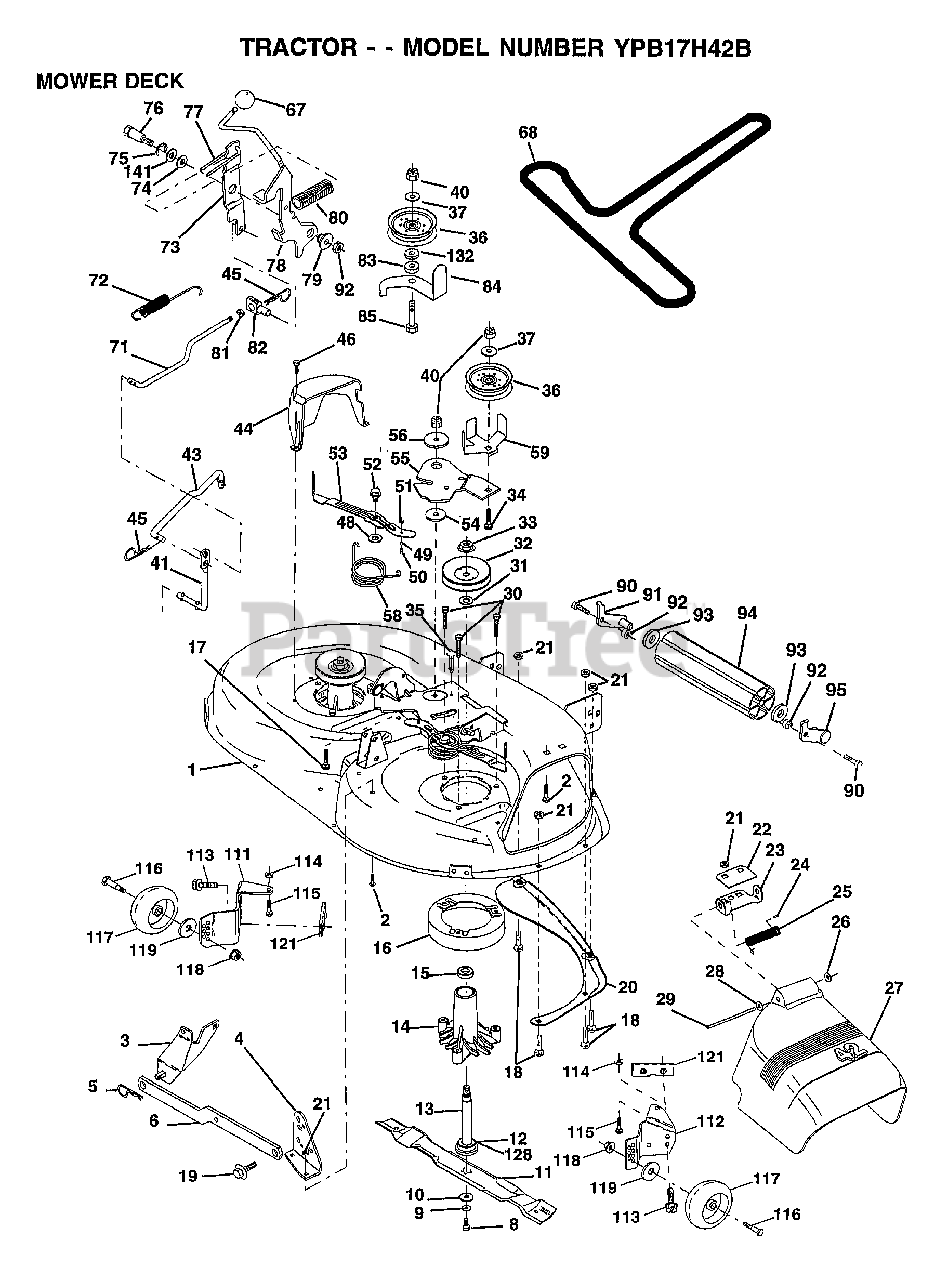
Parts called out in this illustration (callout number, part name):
1	"HOUSING ASSY.42"""
2	BOLT
3	BRKT ASM SWAY BAR
4	BRKT DECK SW BAR
8	BLADE BOLT
10	WASHER.HARD.BLADE
11	"BLADE.42"" HIPERF"
12	BEARING.BALL
14	HSG ASM MANDREL
15	BEARING
16	STRIPPER RND MWR
17	BOLT RDHD 3/8-16
18	BOLT
19	BOLT SHD 5/16-18
20	BAFFLE VORTEX 42
22	STIFFENER BRKT
23	DEFLECTOR BRKT
24	CAP-SLEEVE LT
25	SPRING TORSION
26	NUT PUSH M
27	DEFLECTOR.SHIELD
28	WASHER
29	HINGE ROD
30	"SCREW-THD ROLL,WA"
31	WASHER
32	PULLEY.MANDREL.42
34	BOLT
35	XMAS TREE FASTNER
36	FLAT IDLER PULLEY
37	WASHER
41	PIVOT ROD
43	ROD CLUTCH W/NIBS
44	GUARD MAND LH BLK
45	RETAINER M
46	SCREW.1/4-20X5/8
48	HARD SMALL WASHER
49	ROLLER ASM-CAM
50	SHOULDER BOLT
51	LOCKNUT
52	BOLT.SHLD.5/16-18
53	BRAKE PAD ARM ASM
54	HARDENED WASHER
55	ARM-IDLER
56	SPACER.RETAINER.MOWER
58	SPRING TORSN BRAK
59	GUARD IDLER TUV
67	KNOB.RD.7/16-14
68	BELT.V.T-PATH
71	ROD CLUTCH 38/42
72	RETURN SPRING
73	CLUTCH ARM SECOND
74	WASHER
75	RING
76	SHOULDER BOLT
77	SPRING KEEPER
78	LEVER.ASM.CLUTCH
79	BUSHING
80	SPRING.CLUTCH.MWR
81	NUT
82	TRUNION ADJ
83	WASHER
84	"KEEPER-BELT,FIXED"
85	BOLT
90	BOLT
92	NUT
93	WASHER
111	BRACKET.GWHL.LH.
112	BRACKET.GWHL.RH.
113	SCREW
116	BOLT M
117	WHEEL.GUAGE
118	LOCKNUT
119	WASHER
121	BRACKET.EXTRD.GWL
128	WASHER.FELT.
132	WASHER GT
141	WASHER .T
